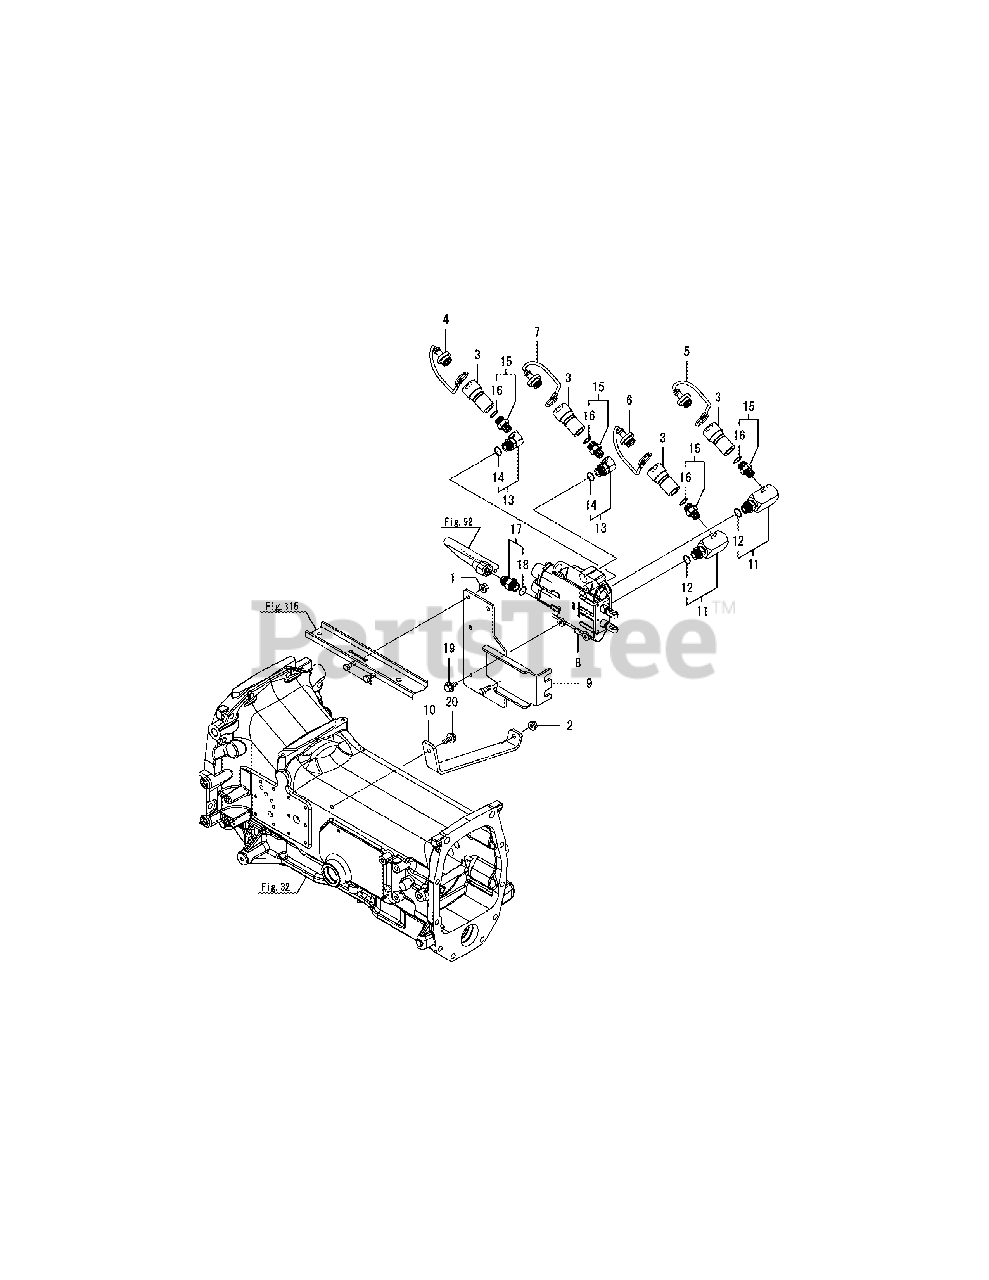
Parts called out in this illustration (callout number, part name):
1	NUT W/WASHER 8
2	NUT W/WASHER 8
3	COUPLER,QUICK 3/8F
4	PLUG, DUST RED
5	PLUG, DUST BLUE
6	PLUG, DUST YELLOW
7	PLUG, DUST GREEN
9	SUPPORT ASSY, VALVE
11	ELBOW/HYD, 3/4UNF-L
13	ELBOW/HYD, 3/4UNF
15	JOINT/HYD,3/4UNF-3/8
17	FITTING/HYD, 3/4-7/8
19	BOLT M 8X 12 PLATED
20	BOLT M 8X 20 PLATED
